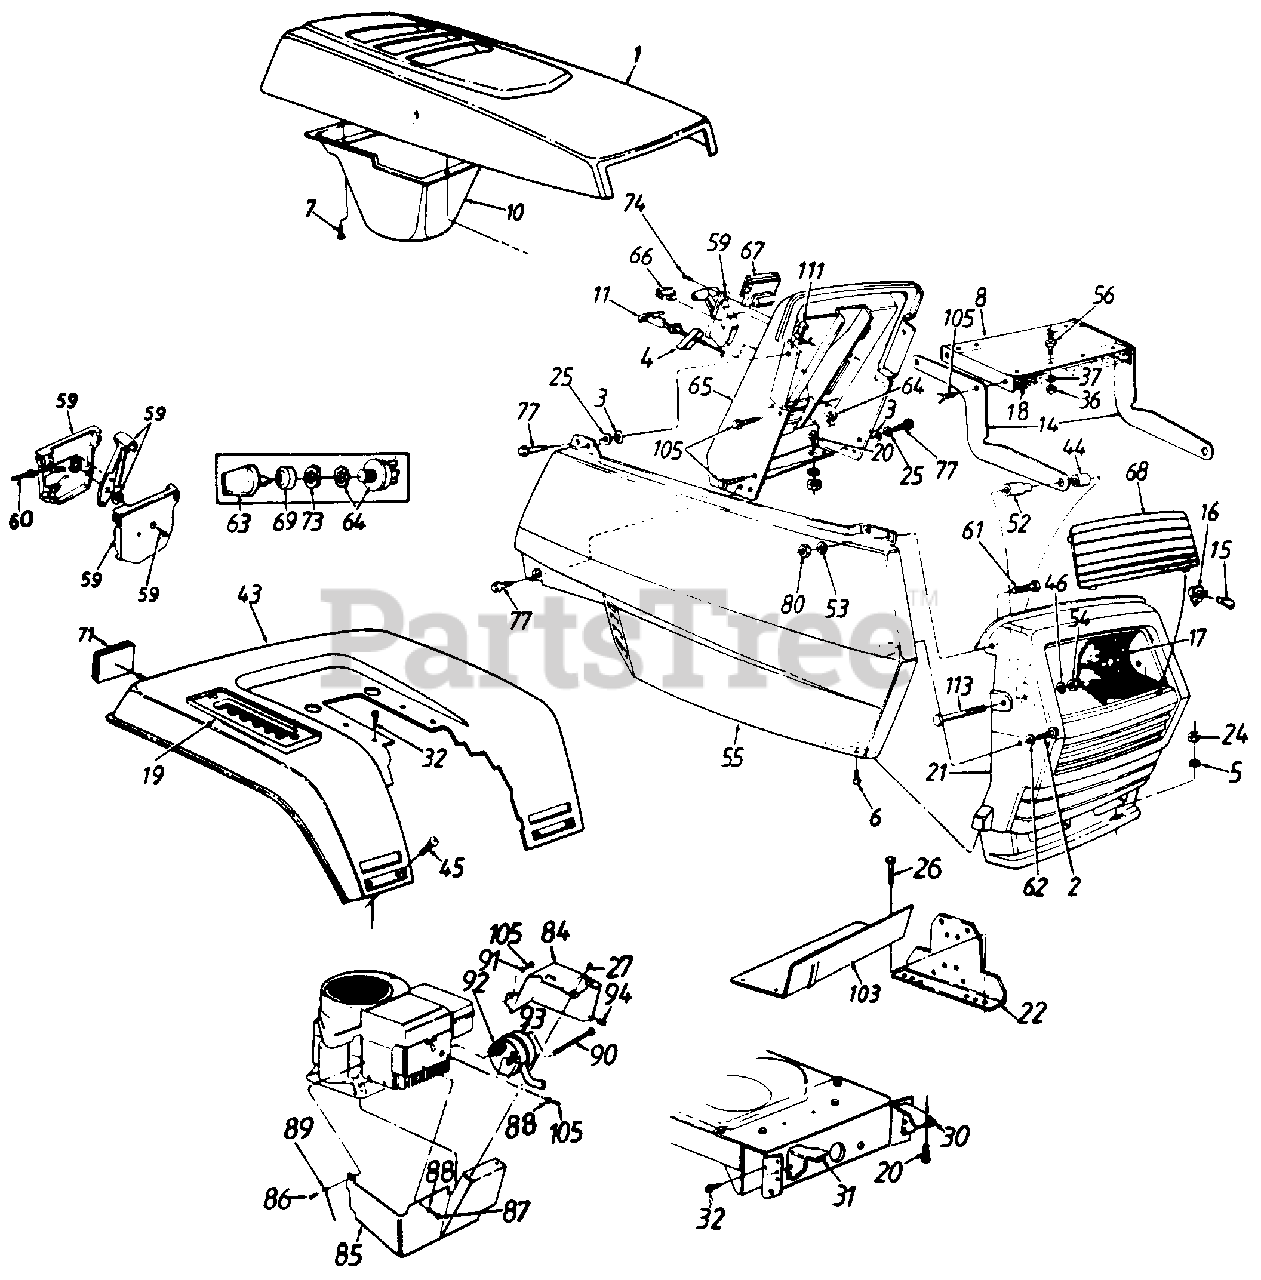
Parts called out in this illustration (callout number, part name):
3	Bolt Retainer 1/4" I.D.
4	Retainer Clip
5	Fl-Wash. .34" I.D. x .68"
6	Truss Mach. B-Tap Scr. #10 x .5" Lg.
7	Hex Wash. Hd. AB-Tap Scr. #8 x .5" Lg.
11	Choke Control 29" Lg.
14	Hood Hinge
15	Lamp
16	Twist Lock - Lamp Socket
17	Reflector - Headlight
21	Grille
24	Hex Nut 5/6-18 Thd.
25	Fl-Wash. 1/4" I.D. x .93" O.D.
26	Hex Wash. Hd. B-Tap Scr. 5/16-18 x .5" Lg.
27	Hex B-Tap Scr. #10 x .38" Lg.
30	Grille Mount Brk't.- L.H.
31	Grille Mount Brk't.- R.H.
32	Hex Wash. Hd. AB-Tap Scr. 5/16 x .75" Lg.
36	Hex Nut 1/4-20 Thd.
37	Bell-Wash. .265" I.D. x .75"
43	Rear Fender
44	Spacer .33" I.D. x .625" O.D.
45	Carriage Bolt 1/4-20 x .50" Lg.
46	Fl-Wash. .328" I.D. x .68" O.D
52	Shld. Spacer.33" I.D.
53	Fl-Wash. .281" I.D. x .5" O.D.
54	Hex Cent. L-Nut 5/16-18 Thd.
55	Side Cover - R.H.
56	Double Ended Stud 1/4-20 Thd.
59	Throttle Control Box Ass'y.
60	Throttle Control Wire 18.5" Lg.
61	Hex Bolt 1/4-20 x .62" Lg.
62	Fl-Wash. .281" I.D. x .73" O.D.
64	Ignition Switch
65	Dash Panel
66	Light Switch
67	Ammeter
68	Lens
69	Ignition Switch Cap
71	Reflector
73	Ignition Switch Nut
74	Truss Mach. AB-Tap Scr. #10 x .5" Lg.
77	Hex Wash. Hd. Tap Scr. 1/4 x .75" Lg.
80	Hex L-Nut 1/4-20 Thd.
84	Muffler Heat Shield - L.H.
85	Muffler Heat Shield - R.H.
86	Pan Hd. Mach. Scr. 5/16-18 x .75" Lg.
87	Hex Bolt 1/4-20 x 3/8" Lg.
88	Spr. Wash. .265" I.D.
90	Shld. Bolt 7/16" Dia. x 3-5/8" Lg.
91	L-Wash. 1/4" I.D.
92	Gasket
93	Muffler
94	Speed Nut #10-24 Thd.
111	Speed Nut 1/4-20 Thd.
113	Hex Bolt 5/16-18 x 2.75"
